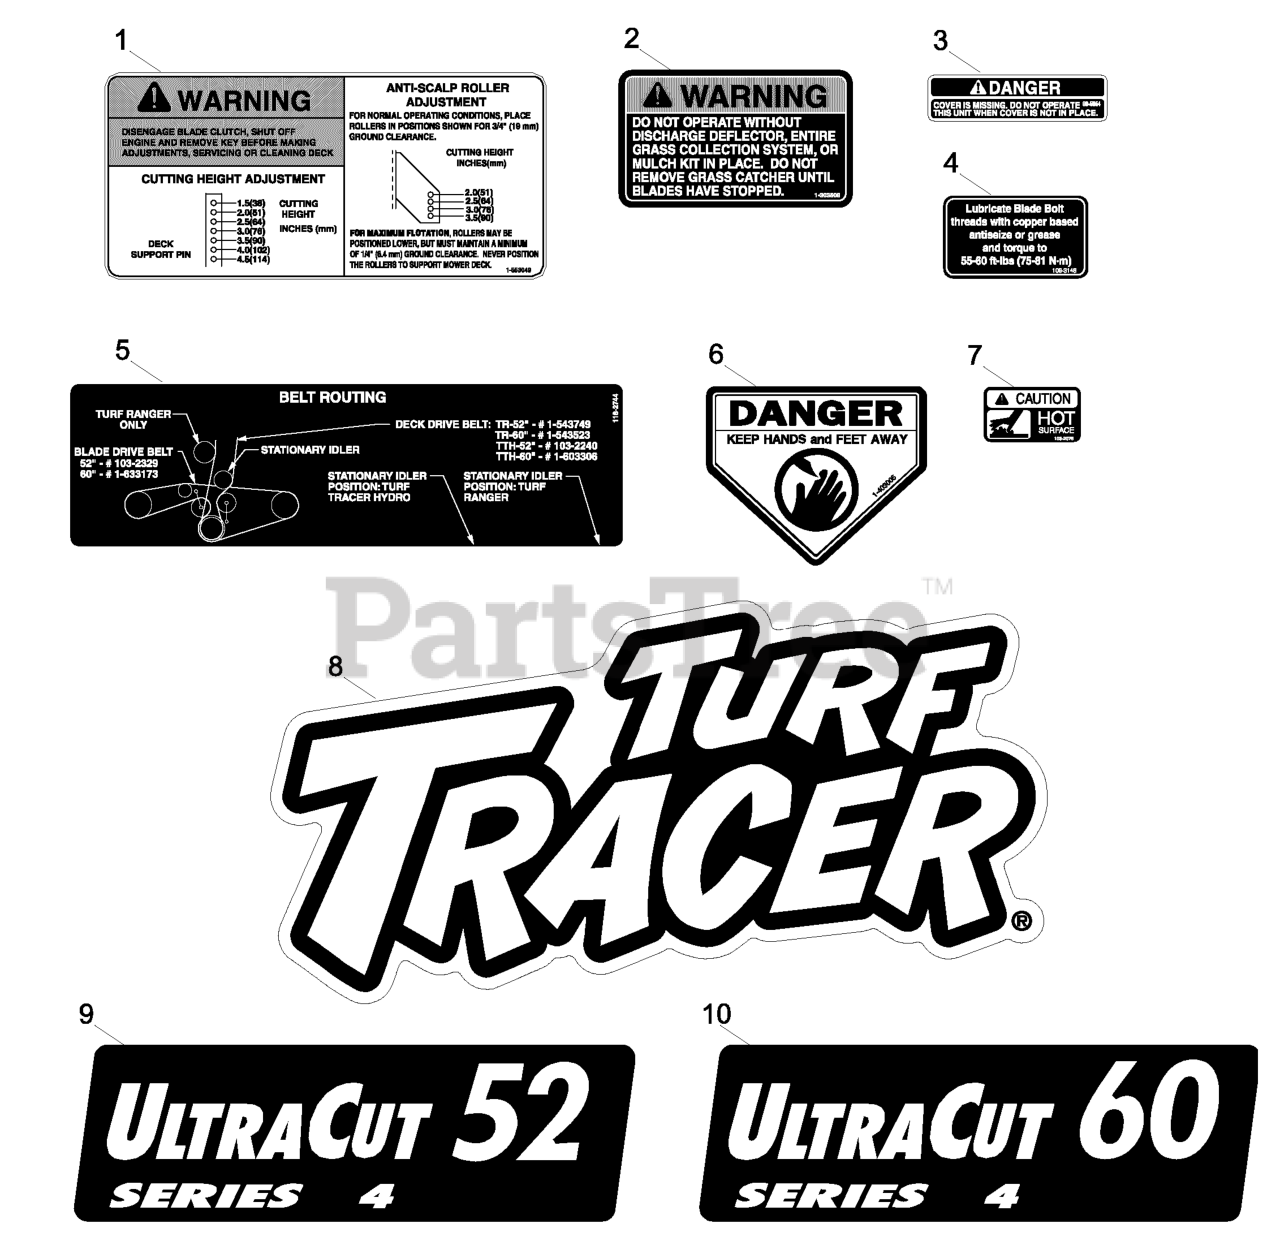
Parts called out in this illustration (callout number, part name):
1	DECAL,ANTI SCALP
2	DECAL-WARNING, DISCHARGE
3	DECAL-COVER, MISSING
4	DECAL,BOLT TORQUE
5	DECAL-BELT ROUTING
6	DECAL-DANGER
7	DECAL-CAUTION
8	DECAL,TTH MODEL
9	DECAL,ULTRACUT 52 SERIES
10	DECAL,ULTRACUT 60 SERIES
